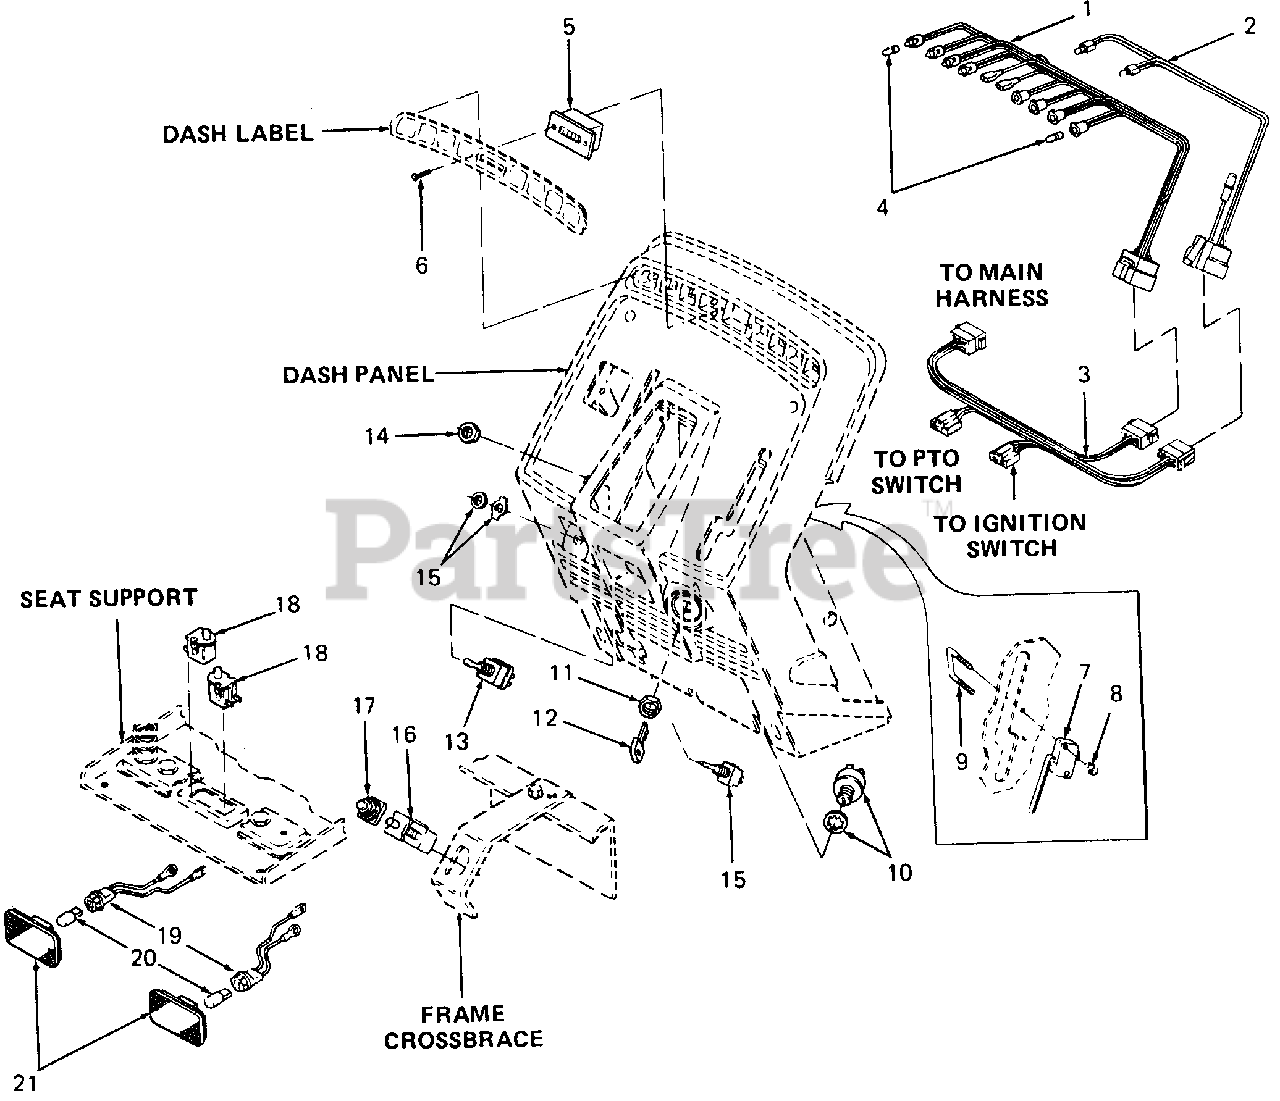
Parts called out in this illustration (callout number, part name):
1	Harness, Indicator Wire
2	Harness, Indicator Adapter
3	Harness, Pedestal
4	Bulb, Indicator
5	Hour Meter
6	Screw, Truss Hd Tapp, #6 X .62 Lg
7	Switch, Reverse
8	Nut, Hex Insert Lock, #4-40
9	Screw, Switch
10	Switch, Ignition
11	Nut, Ignition Switch
12	Key, Ignition (Set of 2)
13	Switch, PTO
14	Nut, Hex, 1/2-27 X .100 Thk
15	Switch, Headlight
16	Switch, Interlock
17	Boot, Switch
18	Switch, Snap Mount Normally Open (Black)
19	Cable Assy, Tail Light
20	Bulb, Tail Light
21	Lens Assy, Tail Light
